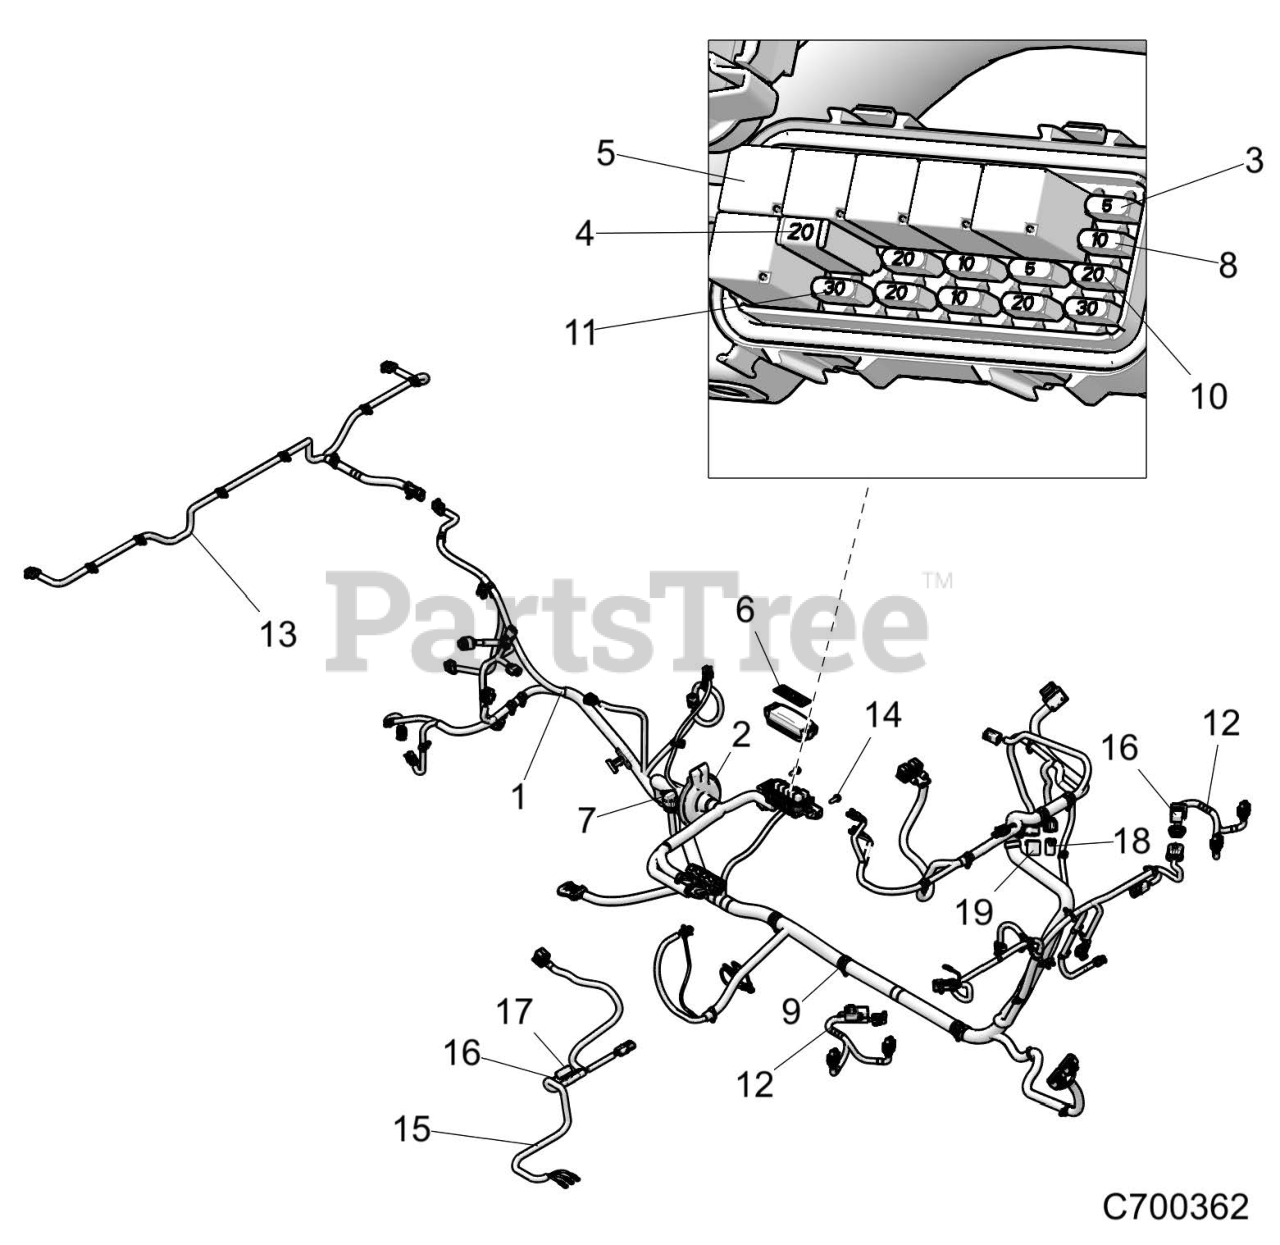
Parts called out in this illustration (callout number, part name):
1	HARNESS-CHASSIS,570,EPS
2	GROMMET-CHASSIS HARNESS
3	FUSE-5A,MINI BLADE
4	BREAKER-CIRCUIT,20 AMP
5	RELAY-SPST,SERIES 303,SEALED
6	DECAL, RELAY/FUSE BLOCK
7	COVER-DIAGNOSTIC,W/CLIP
8	FUSE,IGN.10 AMP,(10)
9	CLIP-ROUTING
10	FUSE,PARK,20 AMP,(10)
11	FUSE,MAIN,30 AMP,(10)
12	HARNESS-HEADLIGHT,ARIENS
13	HARNESS-BOX-ARIENS SPLY
14	SCR-M6X1.0X20,HXHD,FLG,TDFM,BL
15	HARNESS-BOX,LIFT
16	RELAY-MICRO,SPST,35A,SEALED
17	BREAKER-CIRCUIT,20 AMP,SEALED
18	CONNECTOR-CAP,EPS SIGNAL
19	CONNECTOR-CAP,EPS POWER
